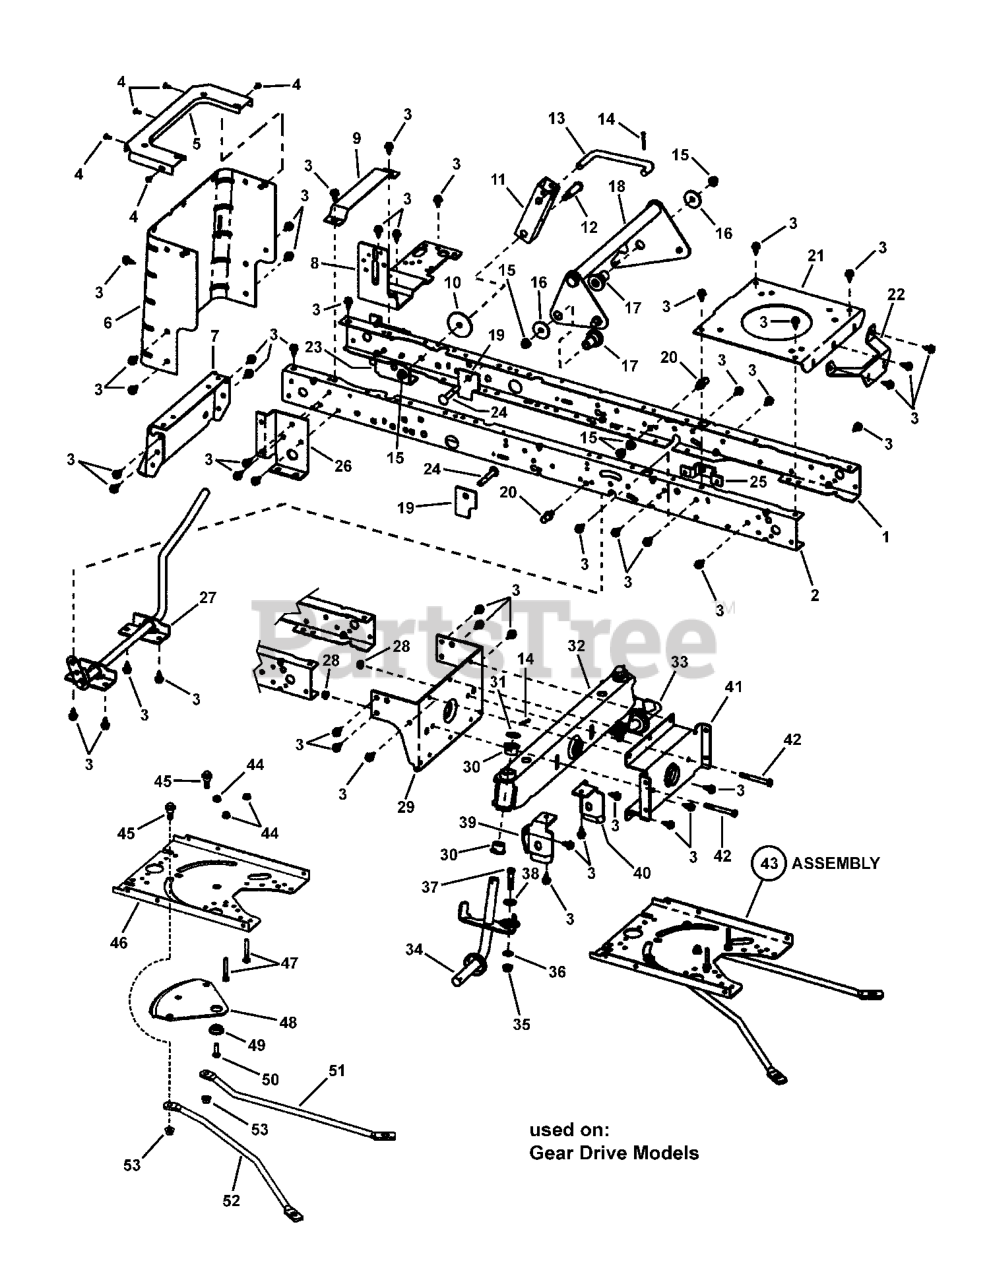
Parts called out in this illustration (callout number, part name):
1	RAIL, FRAME LH
2	RAIL, FRAME RH
3	SCREW, 5/16-18
4	SCREW, 10-24X.50 SELF-TAP SEMS
5	TOP - REAR PLATE
6	PLATE REAR
7	PLATE - HITCH
8	BRACKET SHIFT RH
9	BRKT - BATTERY SUPPORT
10	WASHER, PLAIN .406 X 2.25
11	BRACKET - PIVOT
12	SHOULDER BOLT, 1.563L X 0.75D X 9/16 X 3/8-16
13	LINK - LIFT HANDLE
14	PIN, COTTER 1/8 X 1.25 YZ
15	HFLN, 3/8-16 YZ
16	WASHER, 1-1/2 OD
17	SPACER - LIFTER PIVOT
18	LIFTER ASSY (WELDMENT)
19	PLATE STIFFENING
20	PIN - THREADED SHOULDER
21	PLATE - ENGINE
22	BRACKET, MUFFLER MOUNTING
23	BRACKET - TRANSAXLE L.H.
24	RHSSNB, 3/8CX2-1/2
25	BRACKET - BELLCRANK
26	BRACKET - TRANSAXLE R.H.
27	ASSEMBLY - BRAKE LEVER (WELDMENT)
28	HFLN, 5/16-24 BZ
29	BRACKET - HANGER REAR
30	BEARING SPINDLE
31	WASHER, .77X1.13X.06
32	WELDMENT, AXLE SECTION ASSY
33	WELDMENT - SPINDLE LH
34	WELDMENT - SPINDLE RH
35	NUT, HEX FLANGE, 3/8-16 NC
36	FW, .41 X.82 X 16GA
37	BOLT, HEX, 3/8-16 UNC X 1.50 BRIGHT ZINC
38	WASHER, FLAT, 25/64" ID X 1" OD X 14 GA.
39	HANGER DECK RH
40	HANGER DECK LH
41	HANGER - AXLE
42	BOLT, HEX HEAD, 5/16-24 X 2.75
43	SECTOR GEAR ASSY (GEAR DRIVE - LT)
44	HFLN, 5/16-18 BZ
45	BOLT, SHOULDER 3/8-16
46	PLATE, STEERING MOUNT
47	SCREW - GUIDE
48	GEAR - SECTOR
49	BEARING - SECTOR GEAR
50	HHCS, 5/16-18 X 1 YZ
51	DRAG - LINK LH
52	DRAG - LINK RH
53	HFLN, 3/8-16 YZ
